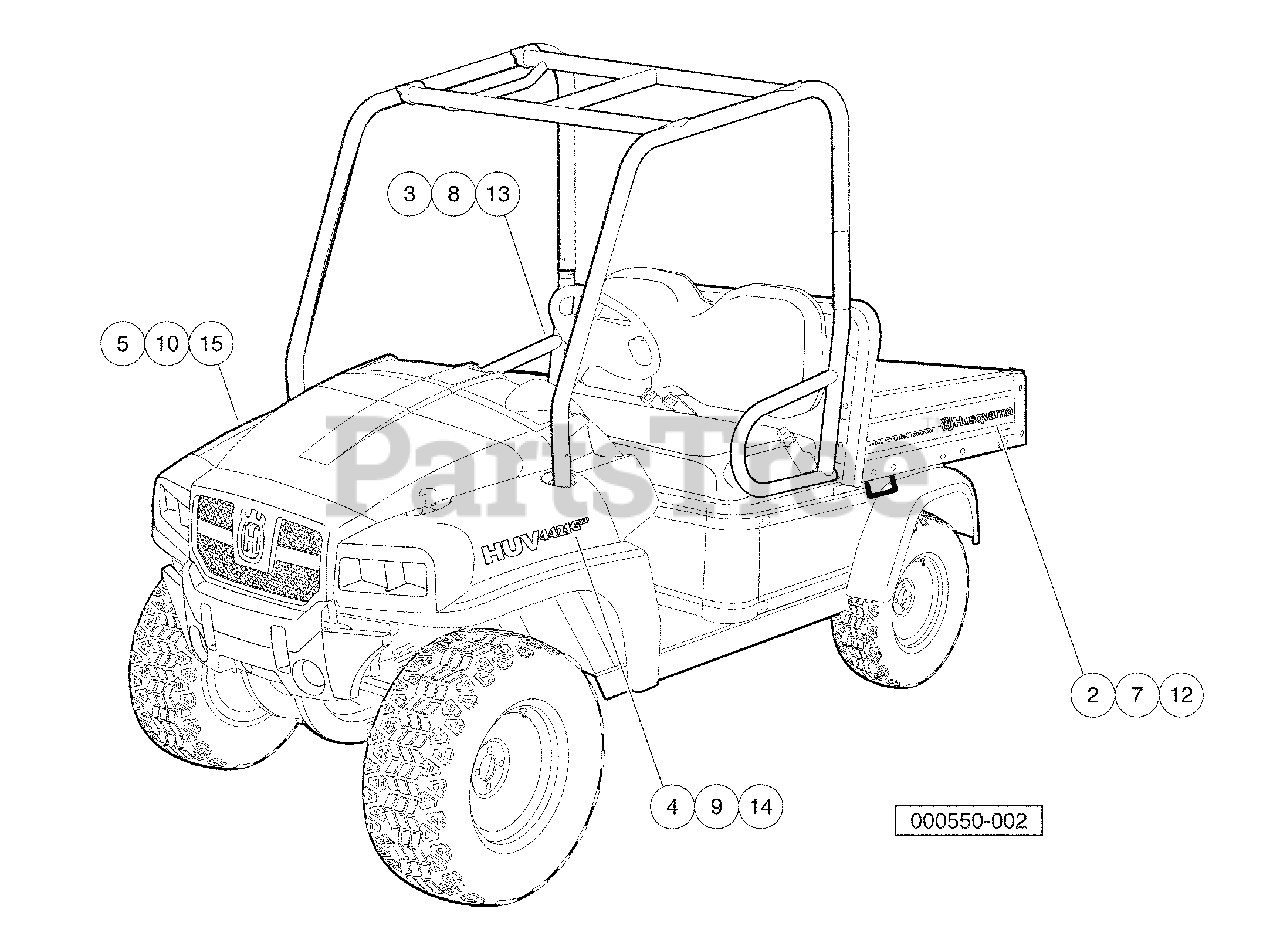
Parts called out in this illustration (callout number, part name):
1	Instl,decal,huv4421gxp,moff
2	Decal, Bed, Huv, Moff, Ds
3	Decal, Bed, Huv, Moff, Ps
4	Decal, Huv 4421gxp, Moff, Ds
5	Decal, Huv 4421gxp, Moff, Ps
7	Decal, Bed, Huv, Orange, Ds
8	Decal, Bed, Huv, Orange, Ps
9	Decal,huv 4421gxp, Orange, Ds
10	Decal,huv 4421gxp, Orange, Ps
11	Instl,decal,huv4421gxp,olv Grn
12	Decal, Bed, Huv, Olv Grn, Ds
13	Decal, Bed, Huv, Olv Grn, Ps
14	Decal,huv 4421gxp, Olv Grn, Ds
15	Decal,huv 4421gxp, Olv Grn, Ps
